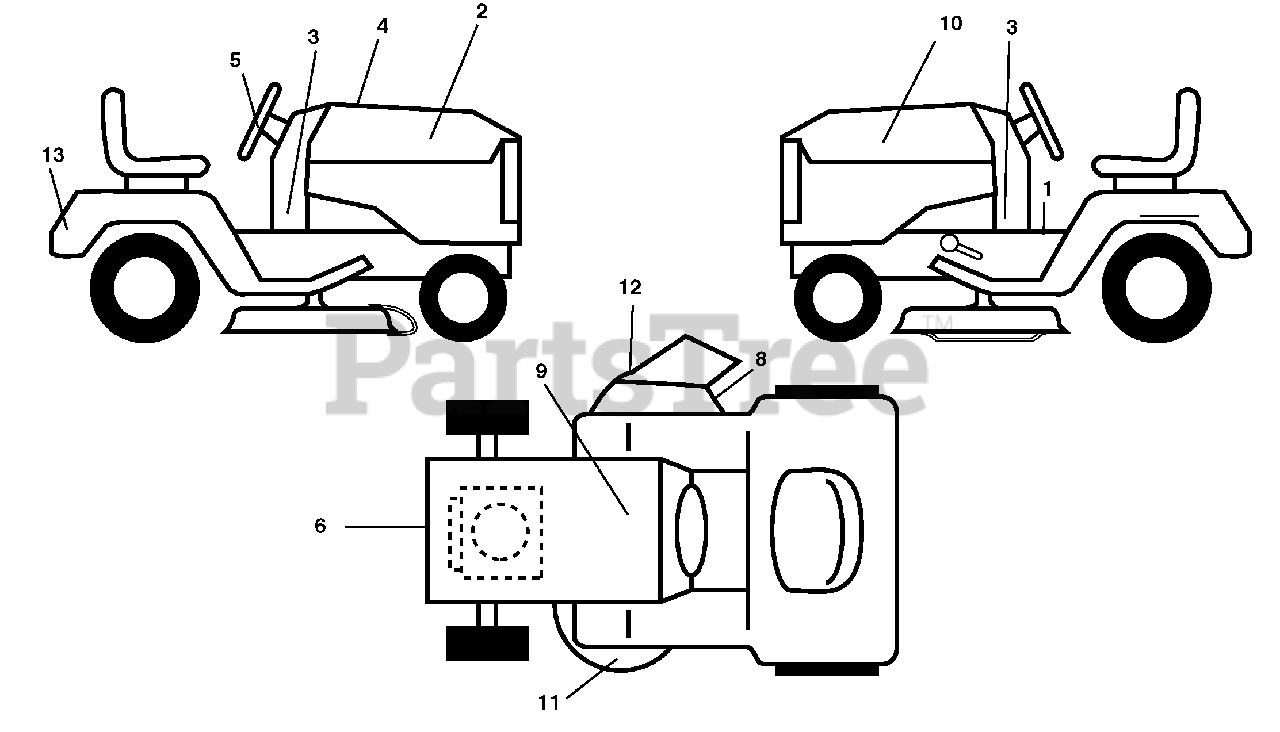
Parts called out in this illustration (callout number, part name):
1	Decal, Operator's
2	Decal, Hood RH
3	Decal, Dash Lower
4	Decal, Replacement
5	Decal, Strg Whl
6	Decal, Engine HP
8	Decal, Mower Sch.
9	Decal, Battery Dnge/Poi
10	Decal, Hood LH
11	Decal, Mower Caution
12	Decal, Mower Warning Keep Hand Away
13	Decal, Fender
13	Decal, Bypass
13	Pad, Footrest, LH
13	Pad, Footrest, RH
13	Manual, Operator's E&SP
13	Manual, Parts
